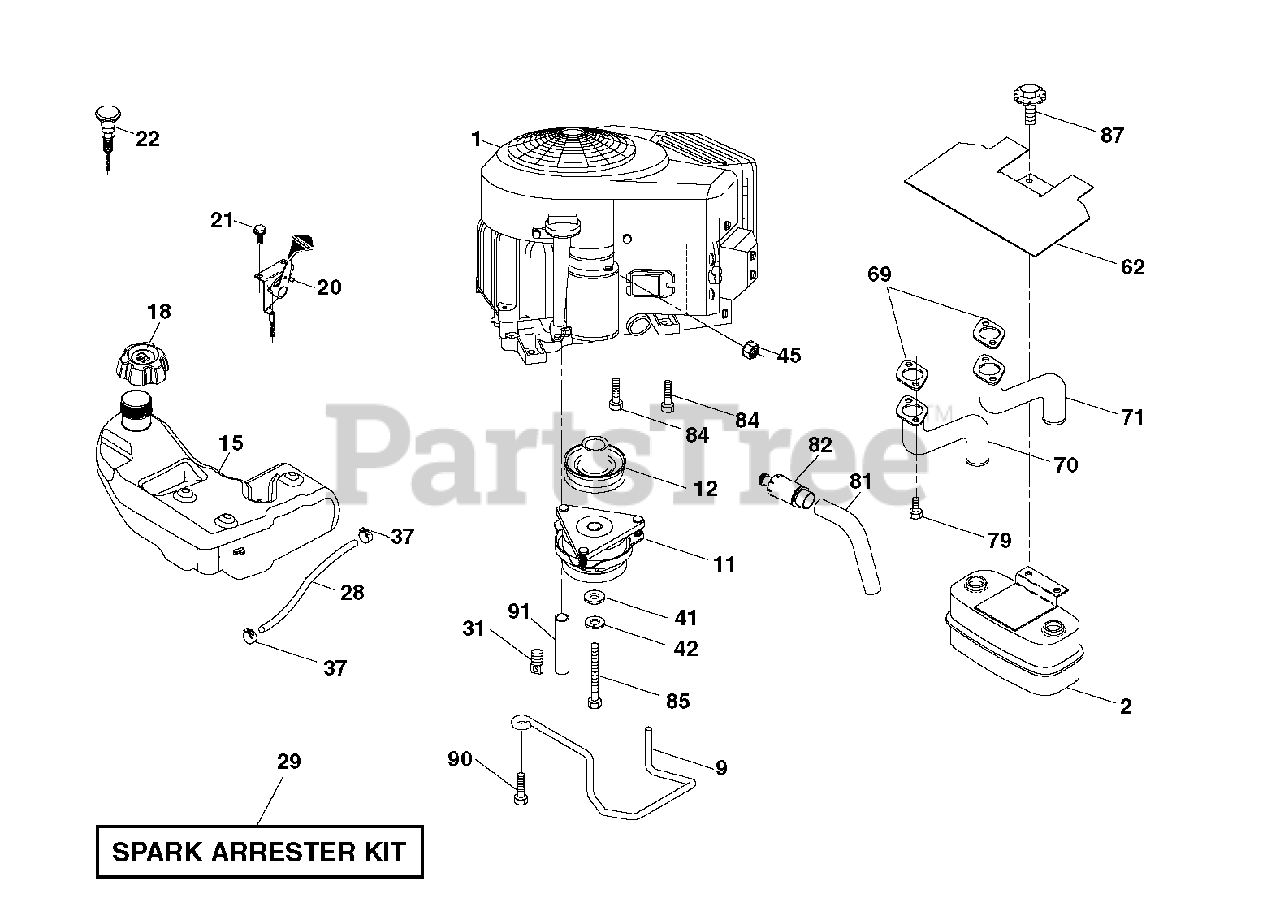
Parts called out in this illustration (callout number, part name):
2	MUFFLER.TWIN.CYL.LOW.TONE
9	KEEPER.BELT.ENGINE.3.25
11	CLUTCH ELECTRIC
12	PULLEY.ASM.ENGINE.1-1/8X3-1/4
15	TANK.FUEL.4GAL
18	CAP.ASM.FUEL.TANK.3"BL
20	THROTTLE CABLE
21	SCREW
22	CONTROL CHOKE
29	ARRESTER SPARK (OPTIONAL)
31	PUSH CLIP
37	HOSE CLAMP
42	LOCKWASHER
45	NUT
62	RP SHIELD HEAT MUFFLER
69	GASKET.MUFFLER
70	TUBE MANIFOLD LH
71	EXHAUST TUBE RH
79	SCREW.SOCKET.HEAD.5/16-18
81	TUBE, DRAIN OIL ASM.
82	PLUG DRAIN OIL EASY
84	SCREW.3/8-16
85	BOLT HEX 7/16-20 X 3.75 GR. 5
87	BOLT.5/16-18UNCX1.W/SEMS.BLK
90	SCREW 3/8-16X1
91	BUSHING.1.375OD
